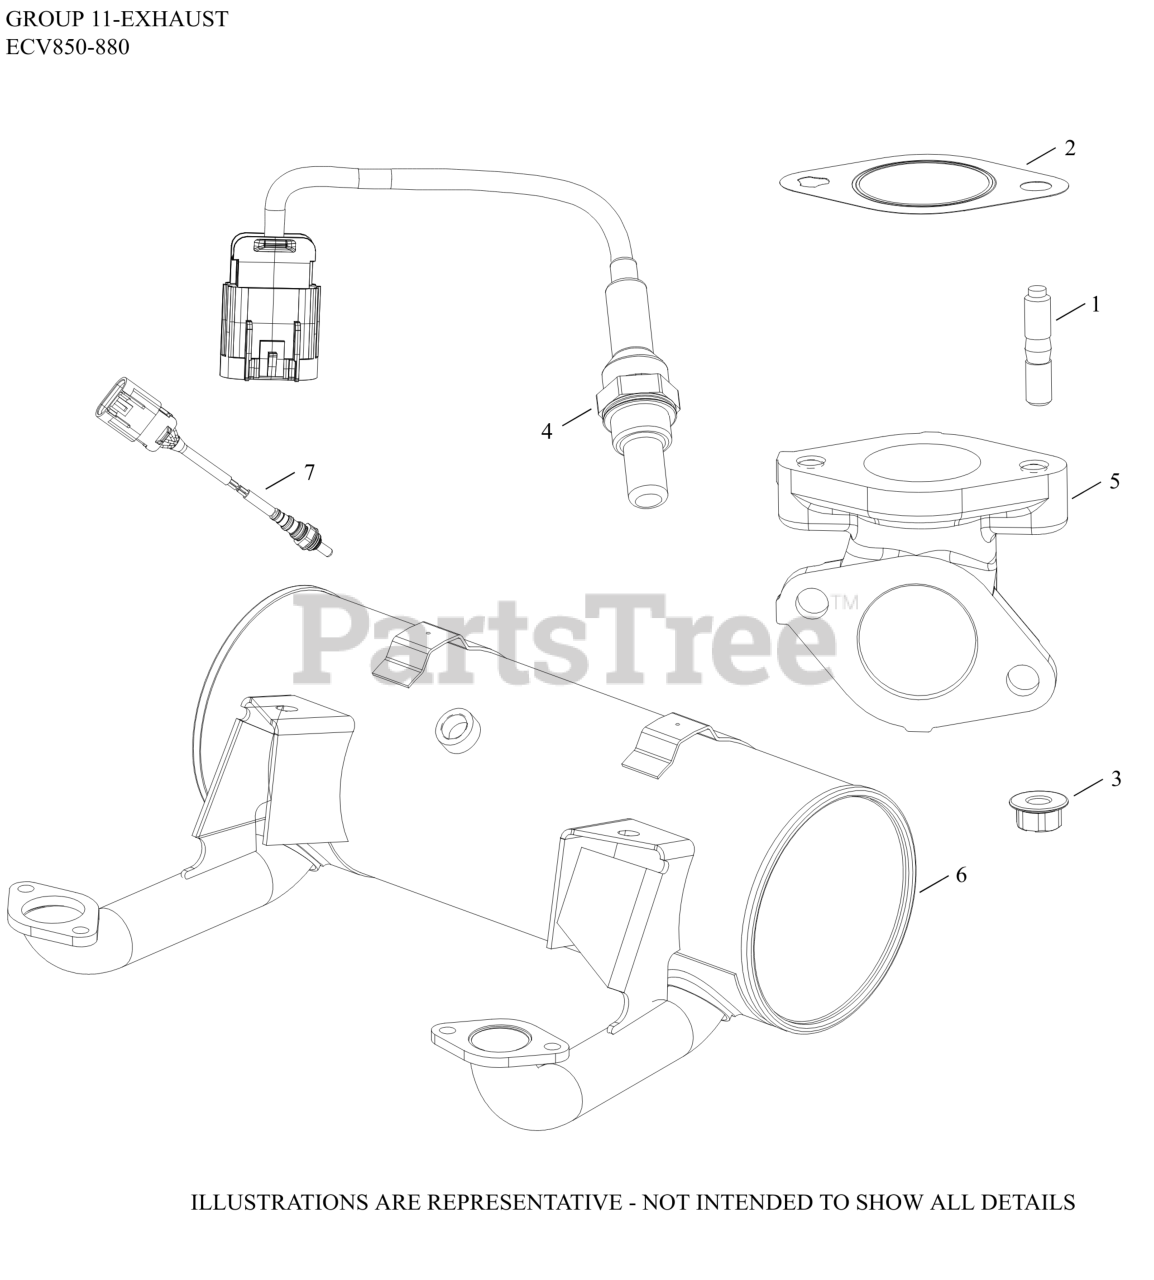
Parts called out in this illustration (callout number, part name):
2	GASKET, EXHAUST MANIFOLD
3	NUT, HEX FLANGE LOCK (M8)
4	SENSOR, OXYGEN-(#2541820S)
